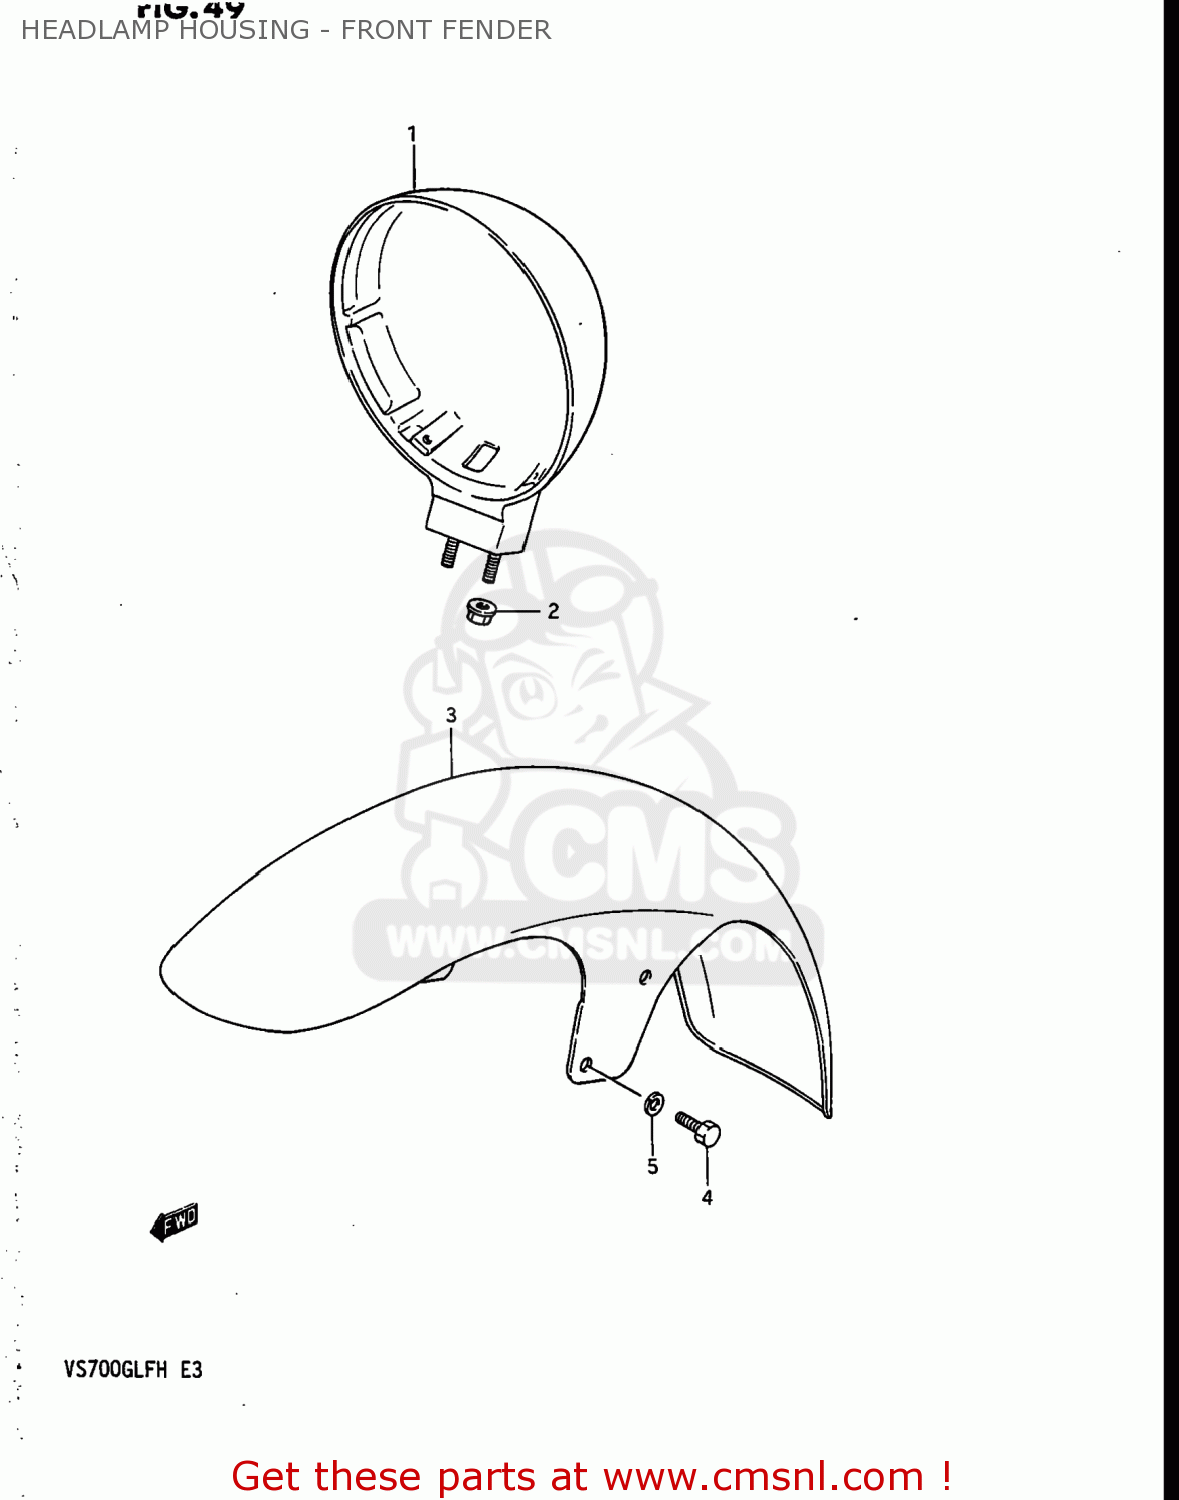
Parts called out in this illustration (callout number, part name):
1	HOUSING,HEADLAMP
2	NUT
3	FENDER,FRONT
4	BOLT
5	WASHER,LOCK
